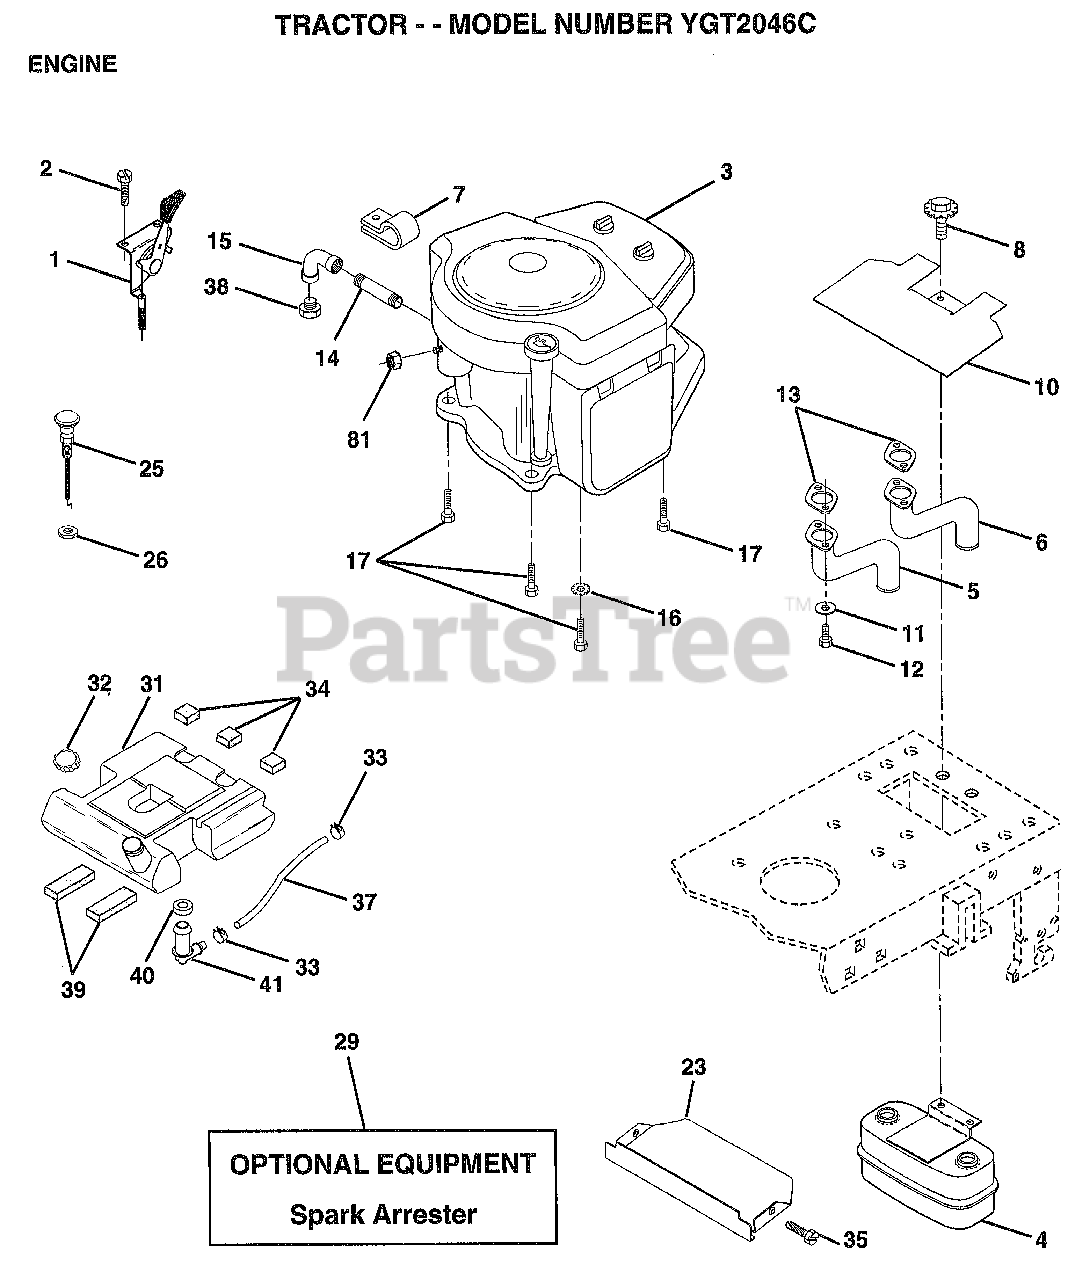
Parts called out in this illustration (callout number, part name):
2	SCREW LT
4	MUFFLER.TW.LOTONE
5	TUBE MANIFOLD LH
6	TUBE MANIFOLD RH
7	"CLIP,INSULATOR"
8	BOLT.5/16-18.UNC
10	SHIELD.BROWNING
11	LOCKWASHER
12	SCREW
13	GASKET MUFFLER
14	PIPE NIPPLE LT
15	ELBOW
16	LOCKWASHER
17	SCREW LT
23	SHIELD.BRN/DBR.GD
25	"CONTROL.CHOKE.51"""
26	"NUT,KEPS 3/8-24IM"
31	TANK FUEL REAR
32	CAP ASM FUEL
33	HOSE CLAMP
34	PAD-SPACER LT
35	SCREW
37	FUEL LINE T
39	PAD IDLER TI
40	BUSHING OUTLET T
41	STEM.TANK.FUEL
81	NUT
